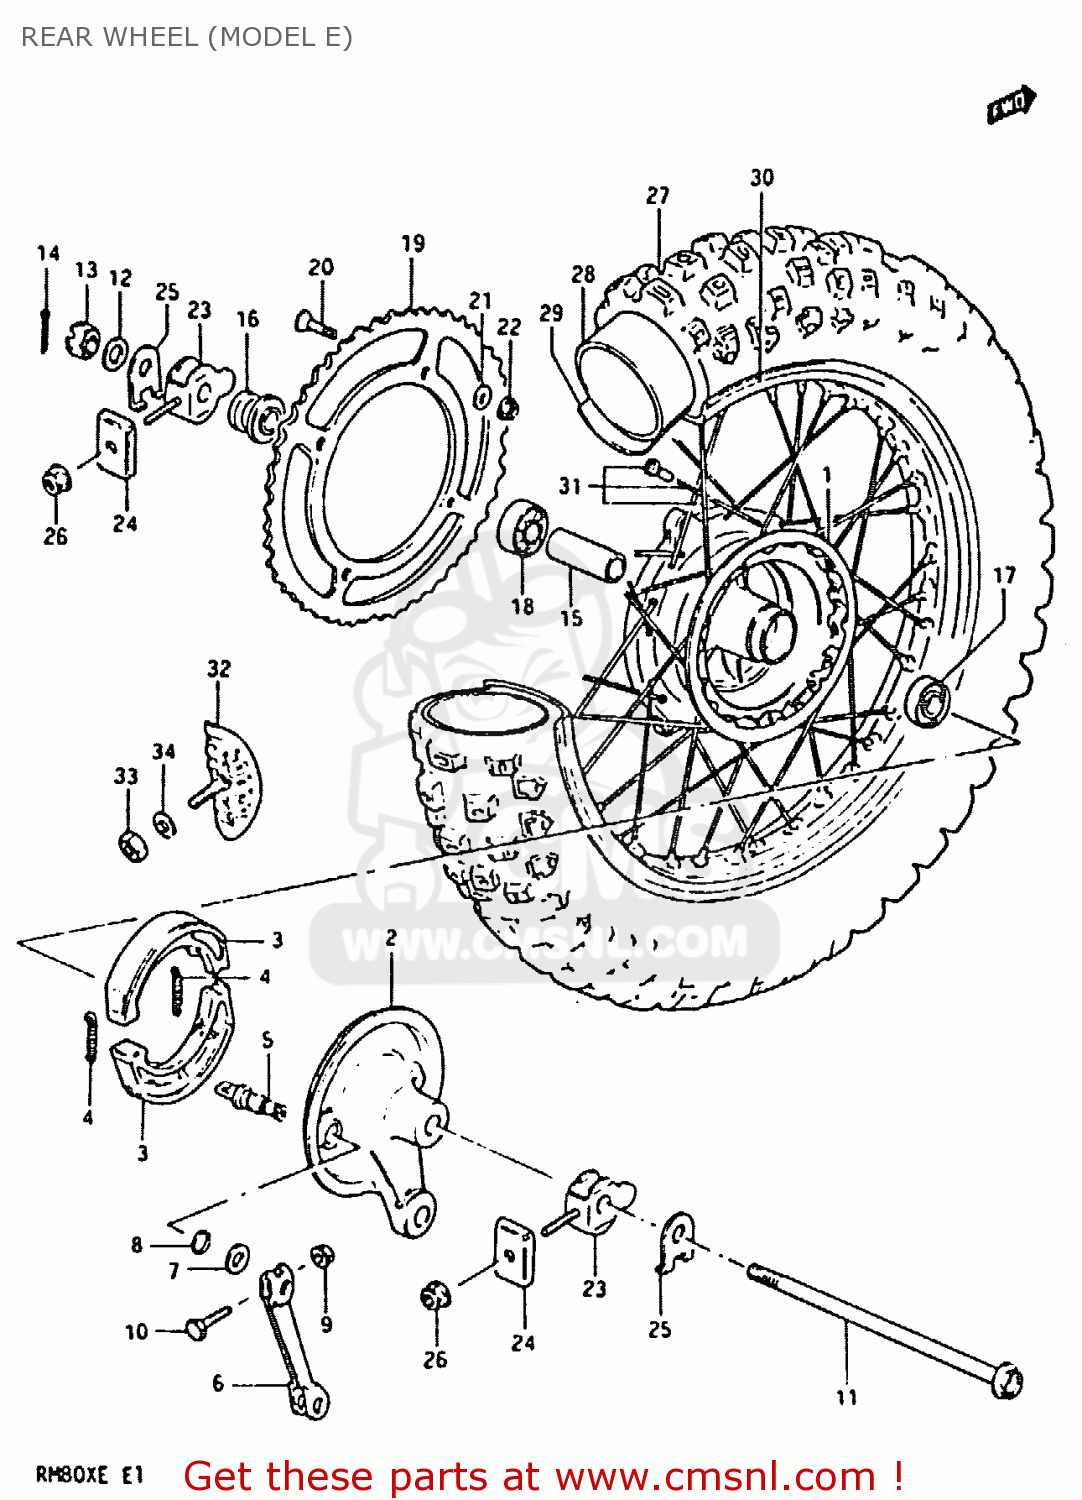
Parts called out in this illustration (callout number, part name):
1	HUB,REAR
2	PANEL,REAR HUB
3	SHOE,BRAKE
4	SPRING(L:35.8)
5	CAM,BRAKE
6	LEVER,RR BRAKE CAM
7	WASHER(12.5X20X1)
8	O RING(D:2.5,ID:11.4)
9	NUT
10	BOLT
11	AXLE,REAR
12	WASHER
13	NUT
14	COTTER PIN
15	SPACER(15.3X21.7X77)
16	SPACER,L
17	BEARING
18	BEARING
19	SPROCKET,REAR
20	SCREW(8X33.5)
21	WASHER
22	NUT
23	ADJUSTER,CHAIN
24	ADJUSTER,CHAIN
25	WASHER,CHAIN ADJUSTER
26	NUT
27	TIRE
28	TUBE ASSEMBLY,WHEEL,INNER
29	PROTECTOR,INNER TUBE
30	RIM,REAR WHEEL (1.60X14)
31	SPOKE SET
32	STOPPER,BEAD
33	NUT
34	WASHER
